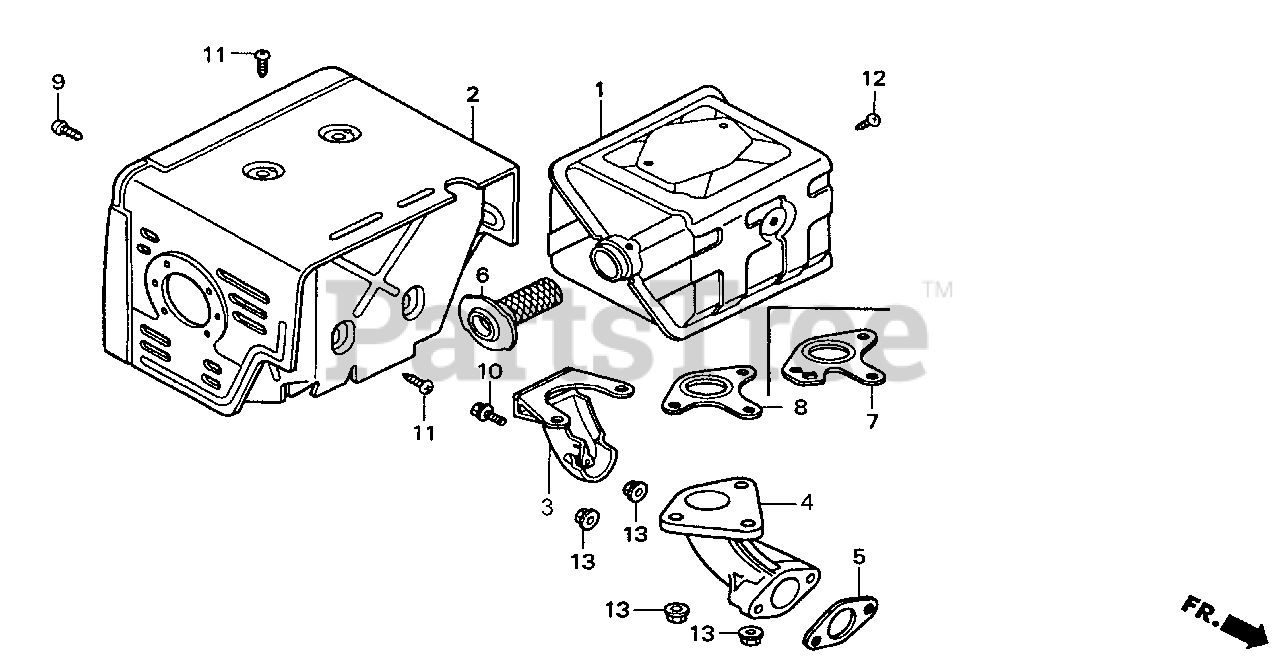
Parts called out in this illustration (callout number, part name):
1	MUFFLER (100DB) (SILENT)
1	MUFFLER (100DB)
2	PROTECTOR, MUFFLER
4	PIPE, EX.
5	GASKET, EX. PIPE
5	GASKET, EX. PIPE (WACKER)
8	GASKET, MUFFLER
9	SCREW, TAPPING (6X10)
11	SCREW, TAPPING (5X8)
13	NUT, FLANGE (8MM)
